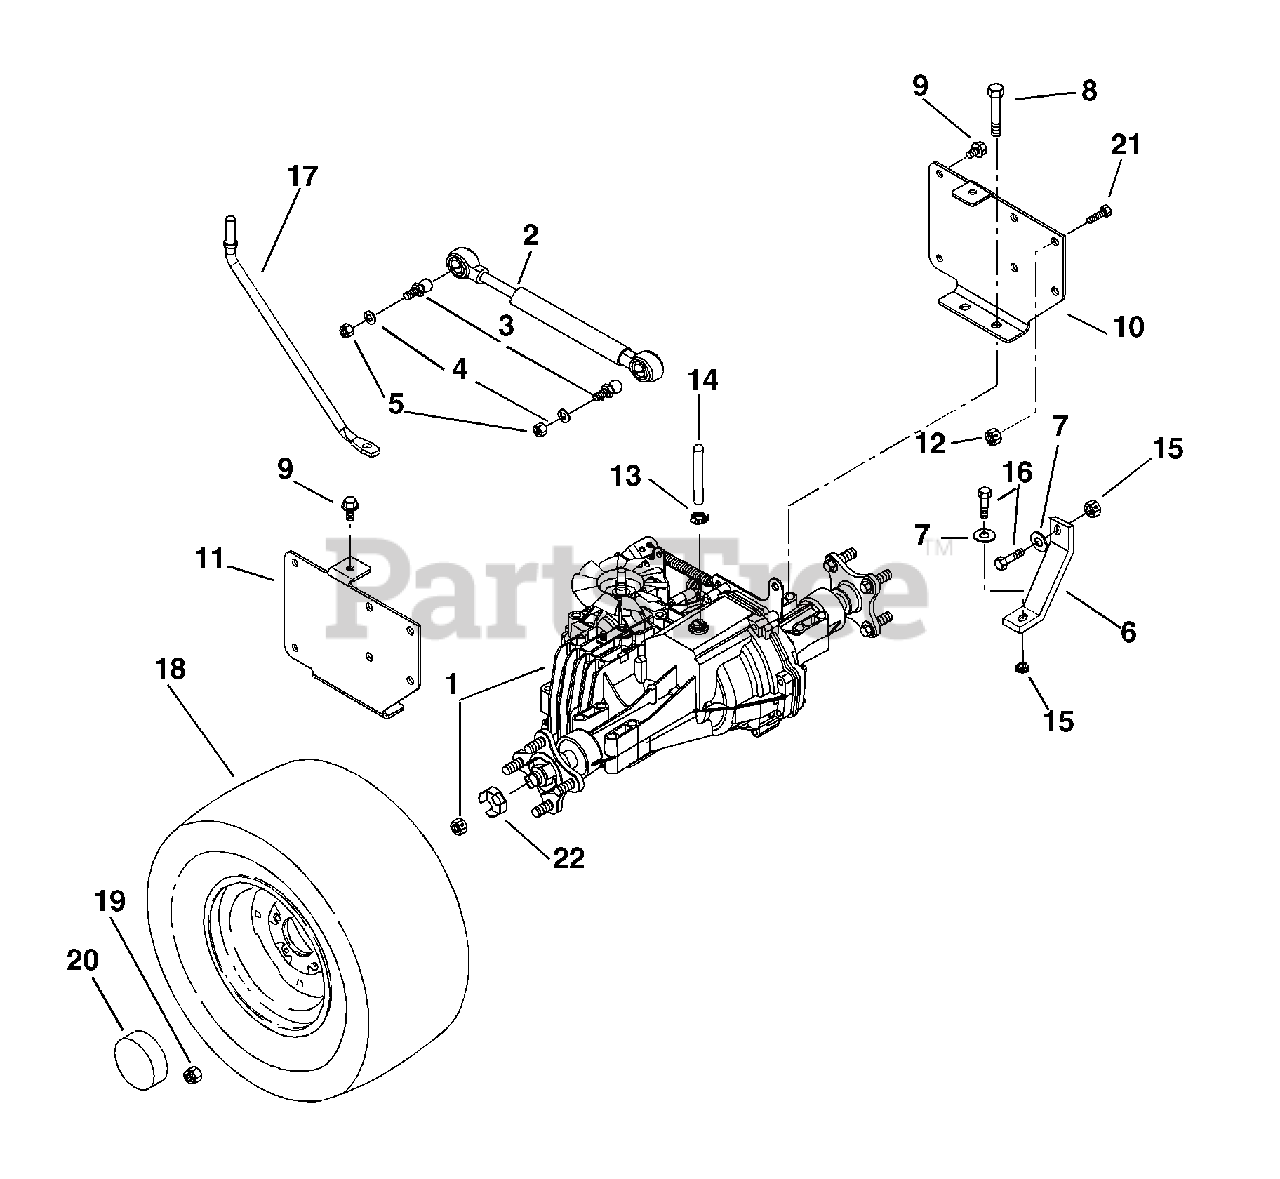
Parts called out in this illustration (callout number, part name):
1	TRANSAXLE-HYDR0-GEAR #319-3000
2	DAMPER - HYDRAULIC
3	STUD- BALL
4	WSHR-LK .312X.097 HVY YWZC
5	@NUT-HEX .31-18 YWZC
6	BRACE, LH TRANSAXLE
7	@WSHR-FL-STL.344X.688X.065YWZC
8	@BLT-HEX .38-16X3.00 GR5 YWZC
9	@SCR-TAP .38-16X.50 HWH TR YWZ
10	MOUNT, AXLE LH
11	MOUNT, AXLE RH
12	@NUT-LK-CTR .38-16 YWZC
13	CLAMP-HOSE WRM .38/.62X.50 #10
14	HOSE, VENT
15	@NUT-LK-CTR .31-18 YWZC
16	@BLT-HEX .31-18X.75 GR5 YWZC
17	ROD-DUMP VALVE
18	TIRE/WHEEL ASSEMBLY 10.50X23
19	NUT-LUG .437-20 YWZC
20	REAR HUB CAP
21	@BLT-HEX .38-16X.75 GR5 YWZC
22	SPINDLE CUP
